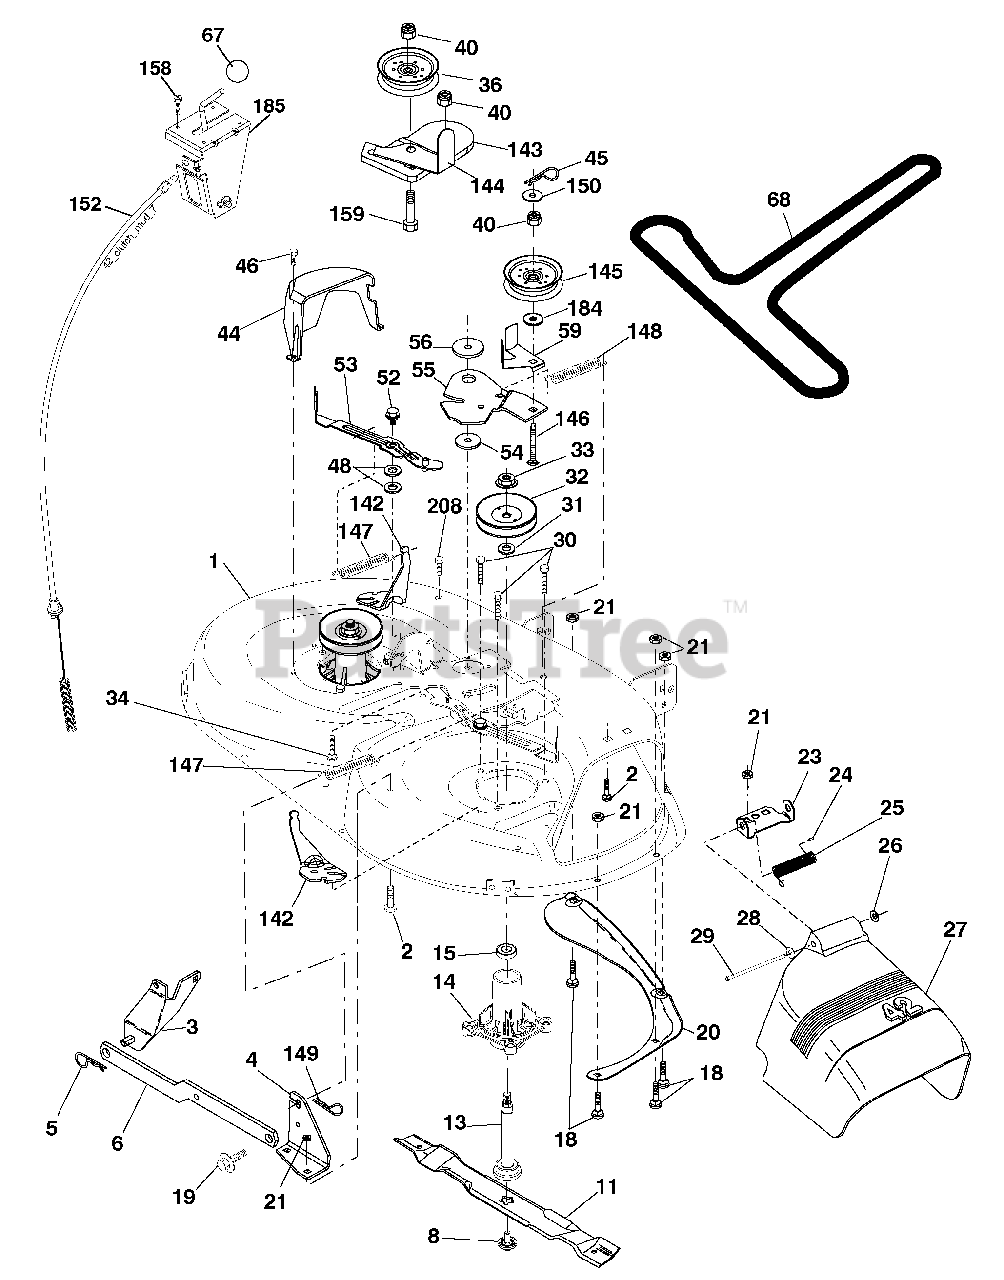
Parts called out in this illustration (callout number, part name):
1	Mower Deck Assembly, 42"
2	Bolt
3	Bracket Asm Fr. Sway Bar 3/42
4	Bracket Asm Deck 42" Sway Bar
5	Retainer Spring
6	Bar Sway Deck
8	Bolt/Washer Asm. 7/16-20 unf (The following Blades are available)
11	Blade Mower 42” Hi-Lift (for bagging and discharging)
11	Blade, Mulching 42” Std (for mulching mowers only)
11	Blade Mulching 42” Premium (For better wear when mulching)
11	Blade 42 3N1
11	Blade 42 3N1 Premium
13	Shaft As m. Mandrel
14	Housing Mandrel
15	Bearing, Ball, Mandrel
18	Bolt, Carriage 5/16-18 x 5/8
19	Bolt, Shoulder
20	Baffle, Vortex
21	Nut
23	Bracket, Deflector Mower 42"
24	Cap, Sleeve 80 x 112 Blk Mower
25	Spring, Torsion, Deflector 2 52
26	Nut, Push Phos & Oil
27	Shield, Deflector 42" Blk
28	Washer 11/32 x 5/8 x 16 Ga.
29	Rod, Hinge 42" 6 75 w/G
30	Screw Thdrol
31	Washer, Spacer Mower Vented
32	Pulley, Mandrel
33	Nut, Toplock
34	Bolt Carr SH 3/8-16 x 1-1/2 Gr.5
36	Pulley, Idler, Flat
40	Nut Lock 3/8-16
44	Guard, Mandrel, LH
45	Retainer
46	Screw, Thdrol 1/4-20 x 5/8 T
48	Washer, Hardened
52	Bolt, Shoulder 5/16-18 unc
53	Arm Assembly, Pad, Brake
54	Washer, Hardened
55	Arm, Idler
56	Spacer, Retainer
59	Guard TUV Idler
67	Knob Round
68	V-Belt, 42" Mower
142	Anchor Spring Brake Mower
143	Bracket Arm Idler 42"
144	Keeper Belt 42" Clutch Cable
145	Pulley Idler Flat
146	Bolt Carriage Idler
147	Spring Extension
148	Spring Return Idler
149	Retainer Spring Yellow
150	Washer 9/32 x 3/4 x 10 Ga.
152	Clutch Cable 42"
158	Screw Hex Thd Cut 1/4-20 x 1/2
159	Bolt Rdhd Sqn 3/8-16 unc x 1-3/4
184	Washer 13/32 x 7/8 x 10 Ga.
185	Head Asm Cable Clutch
208	Screw 3/8-16 x 1/2
208	Mandrel Assembly
208	Replacement Mower, Complete
